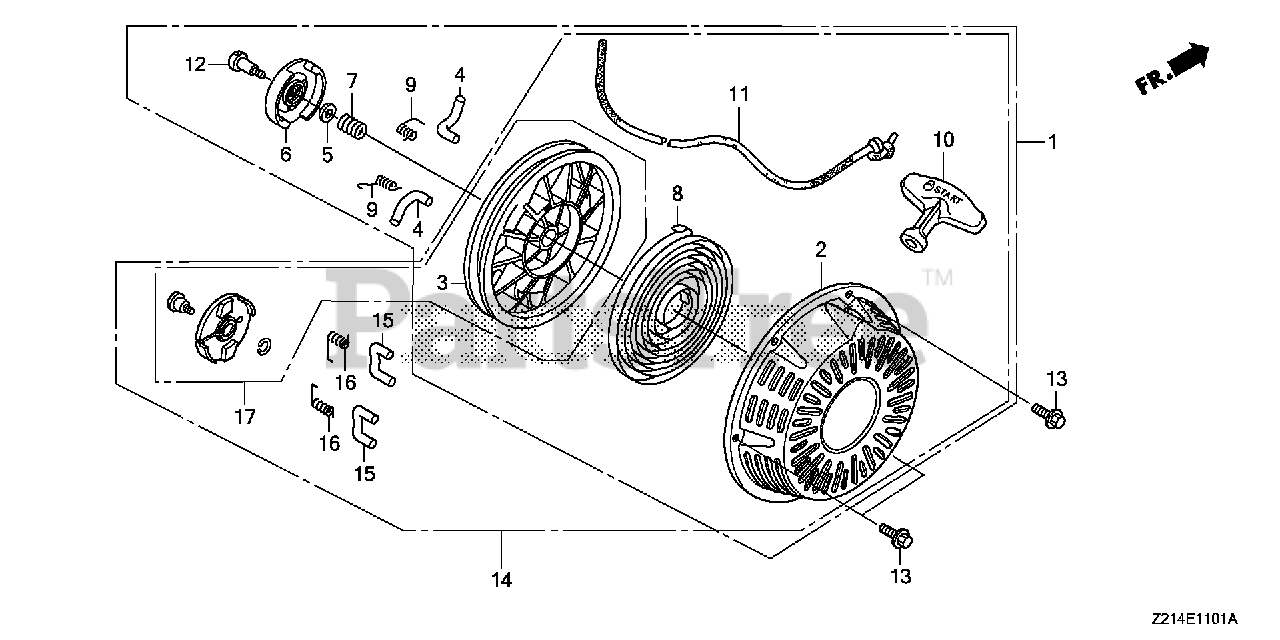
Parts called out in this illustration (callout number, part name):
1	STARTER ASSY., RECOIL *NH1* (BLACK)
2	CASE, RECOIL STARTER *NH1* (BLACK)
3	REEL, RECOIL STARTER
4	RATCHET, STARTER
5	PLATE, FRICTION
6	GUIDE, RATCHET
8	SPRING, RECOIL STARTER
9	SPRING, RETURN
10	GRIP, STARTER
11	ROPE, RECOIL STARTER
12	SCREW, SETTING
13	BOLT, FLANGE (6X10)
14	STARTER ASSY., RECOIL *NH1* (BLACK)
15	RATCHET, STARTER
16	SPRING, RETURN
17	STARTER SET, RECOIL
